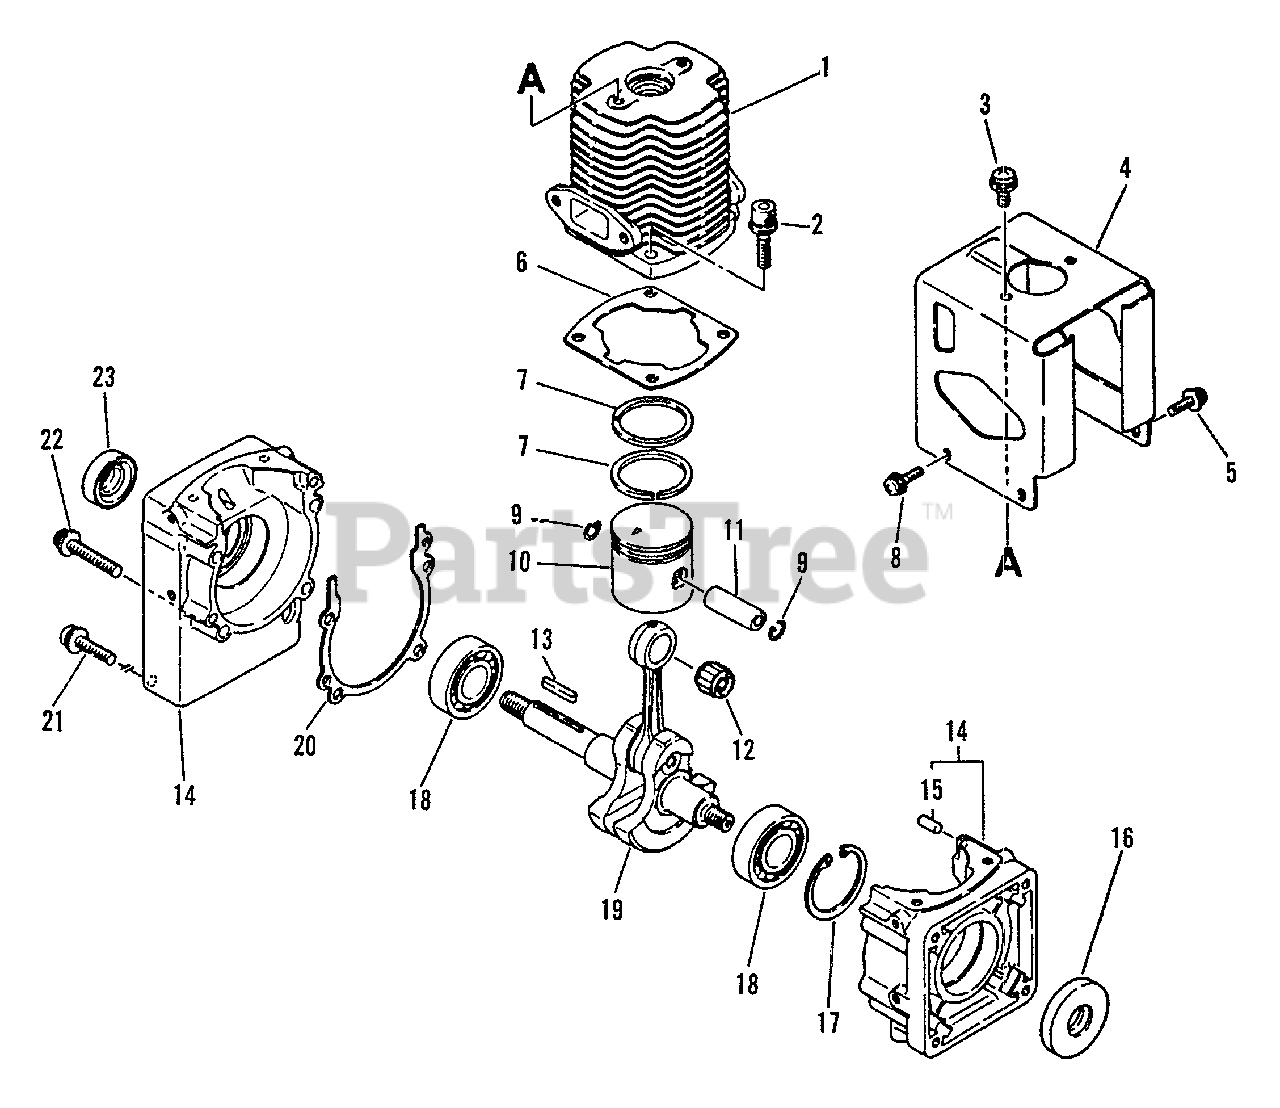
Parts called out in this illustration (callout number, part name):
1	CYLINDER
2	BOLT 5×20
3	SCREW 5×10
4	COVER, CYLINDER
5	SCREW 4×14
6	GASKET, CYLINDER
7	RING, PISTON
8	SCREW 4×12
9	RING, SNAP 8
10	PISTON
11	PIN, PISTON
12	BEARING, NEEDLE
13	KEY
14	CRANKCASE KIT
15	PIN, LOCATING 4
16	SEAL, OIL 18
17	RING, SNAP 35
18	BEARING, BALL 6202
19	CRANKSHAFT
20	GASKET, CRANKCASE
21	SCREW 5×20
22	SCREW 5×30
23	SEAL, OIL
